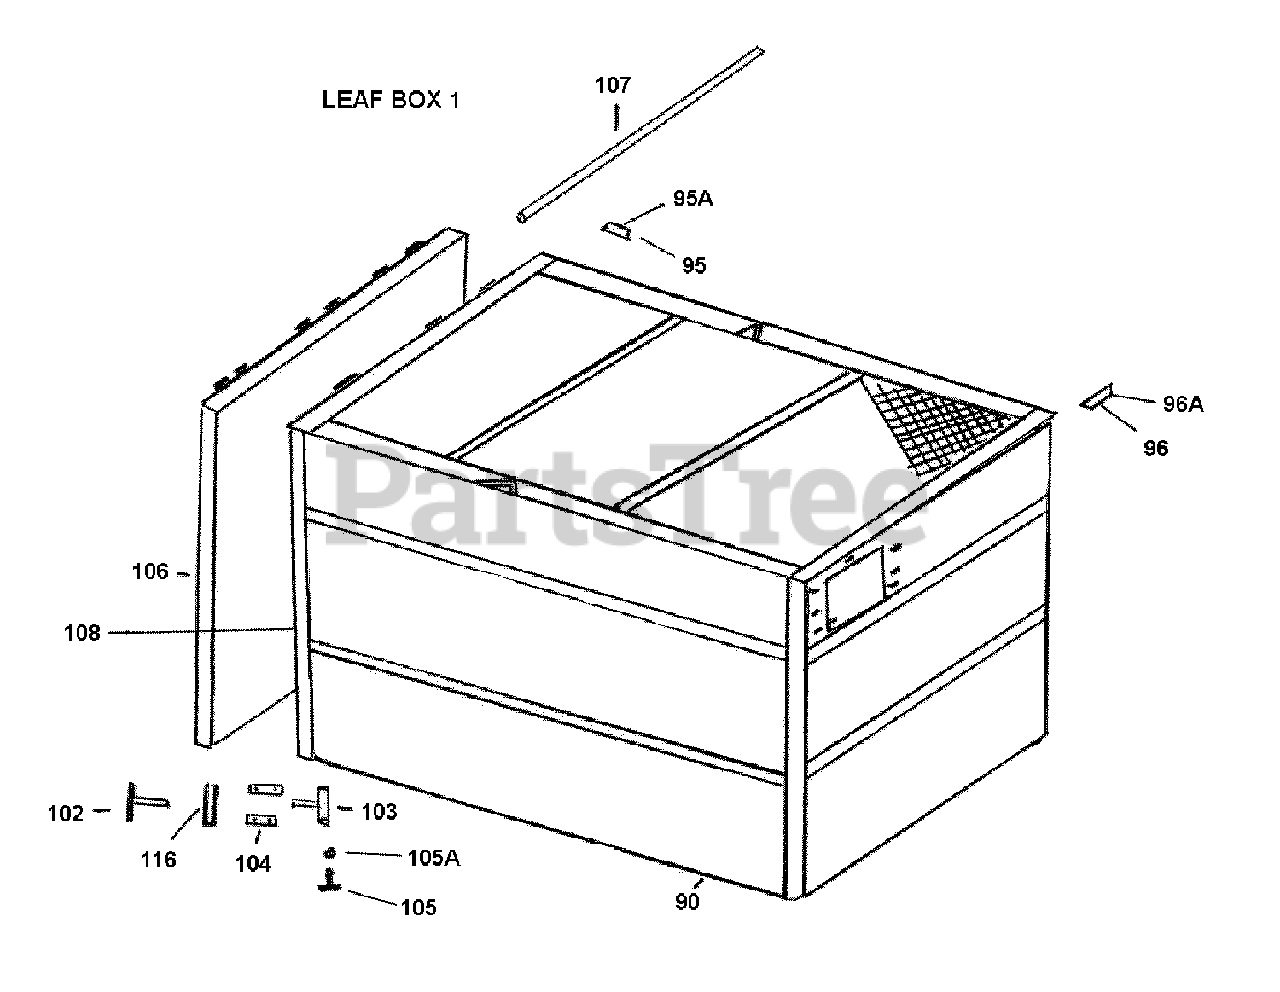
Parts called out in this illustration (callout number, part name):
90	Leaf Box - 10-Cubic Yard
95	Running Light Assembly (cat's eye) - Red
95A	Replacement Lens - Red
96	Running Light Assembly (cat's eye) - Amber
96A	Replacement Lens - Amber
102	5/8-11 Handle Nut
103	Door Lock Pivot T-Bolt
104	Door Lock Side Piece
105	1/2-13 x 4 Hex Bolt
105	1/2-13 x 4-1/2 Hex Bolt
105A	1/2-13 Lock Nut
106	Back Door
107	Back Door Rod
108	Door Gasket
116	Door Latch Holder
